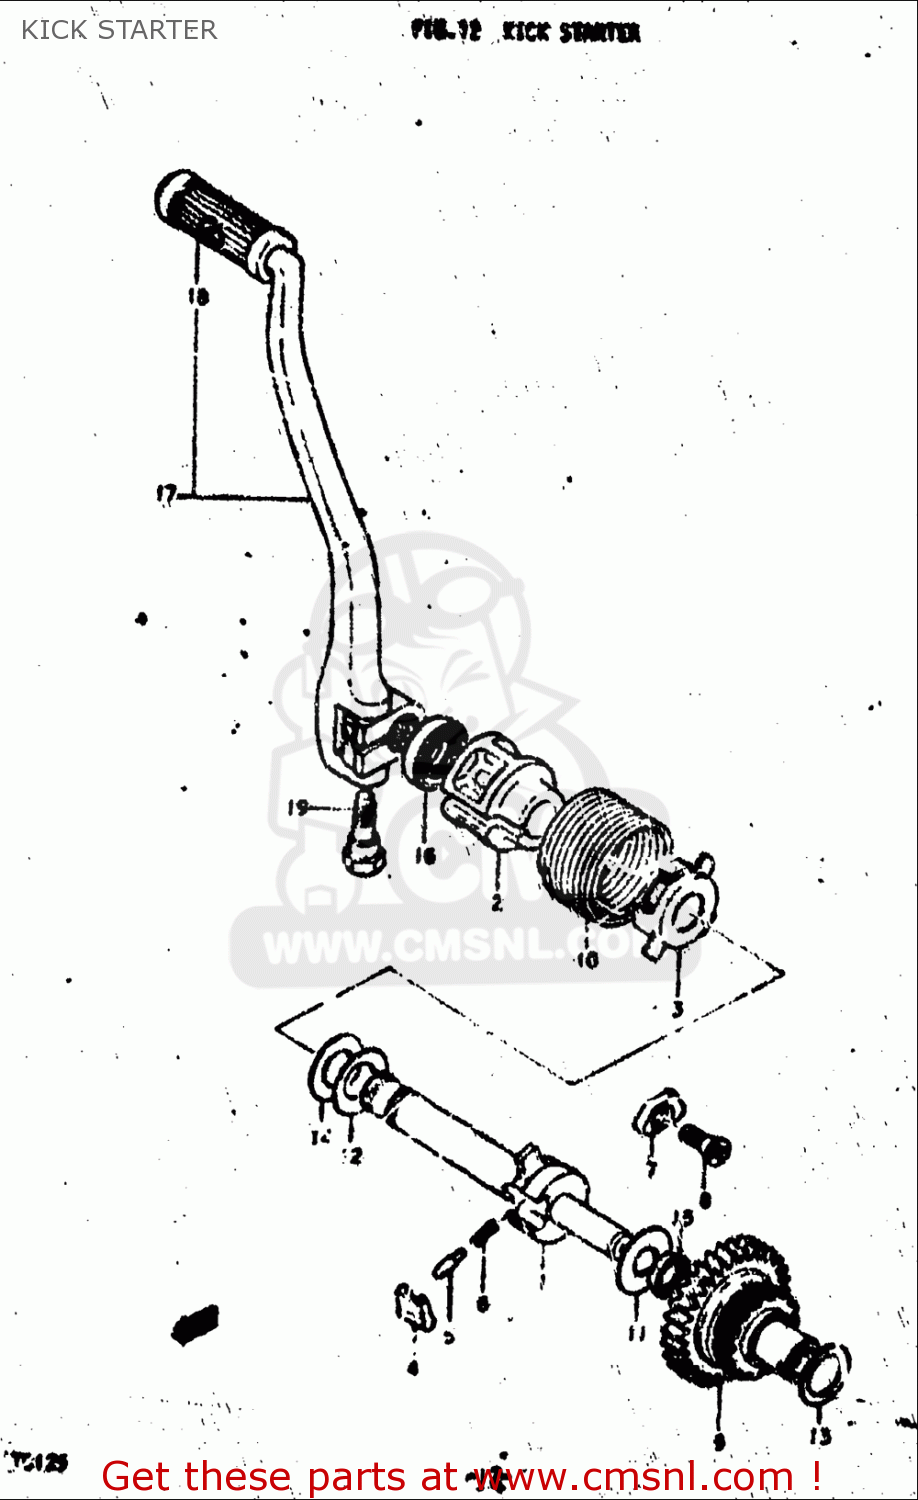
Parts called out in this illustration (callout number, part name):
2	GUIDE,KICK SHAFT SPRING
3	HOLDER,KICK SHAFT SPRING
4	PAWL,KICK STARTER
5	PIN(5X15.5)
6	SPRING
7	LIFTER,KICK STARTER PAWL
8	SCREW(6X19)
9	GEAR,KICK STARTER DRIVE
10	SPRING
11	WASHER
12	WASHER(16X30X0.5)
13	SHIM(20X28X1)
14	WASHER
15	OIL SEAL
16	SEAL,OIL(16X30X8)
17	LEVER ASSY,KICK STARTER
18	RUBBER,KICK STARTER PEDAL
19	BOLT
